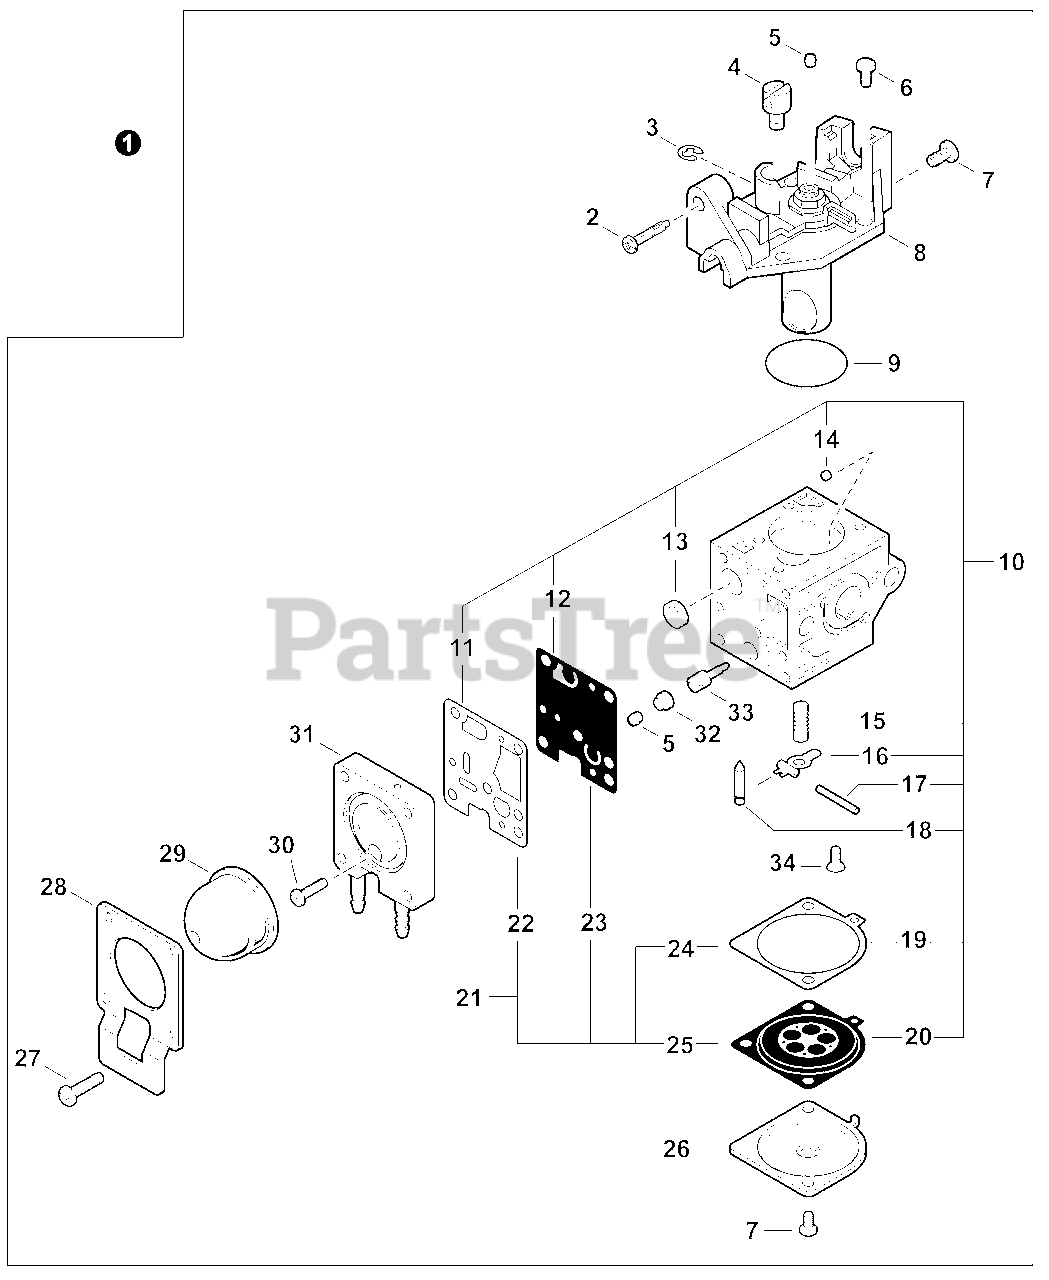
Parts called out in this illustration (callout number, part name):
1	CARBURETOR RB-K119
2	SCREW, IDLE ADJUST
8	COVER ASSY, ROTOR
10	REPAIR KIT, CARBURETOR
11	GASKET, PUMP
12	DIAPHRAGM, PUMP
13	SCREEN, FUEL INLET
14	GUIDE, ROLLER
15	SPRING, METERING LEVER
16	LEVER, METERING
17	PIN, METERING LEVER
18	VALVE, INLET NEEDLE
19	GASKET, METERING DIAPHRAGM
20	DIAPHRAGM, METERING
21	GASKET / DIAPHRAGM KIT
22	GASKET, PUMP
23	DIAPHRAGM, PUMP
24	GASKET, METERING DIAPHRAGM
25	DIAPHRAGM, METERING
26	COVER, METERING DIAPHRAGM
28	RETAINER, PURGE BULB
29	BULB, PURGE
31	BODY ASSY, PURGE
32	CAP, LIMITER
33	NEEDLE, HIGH SPEED
